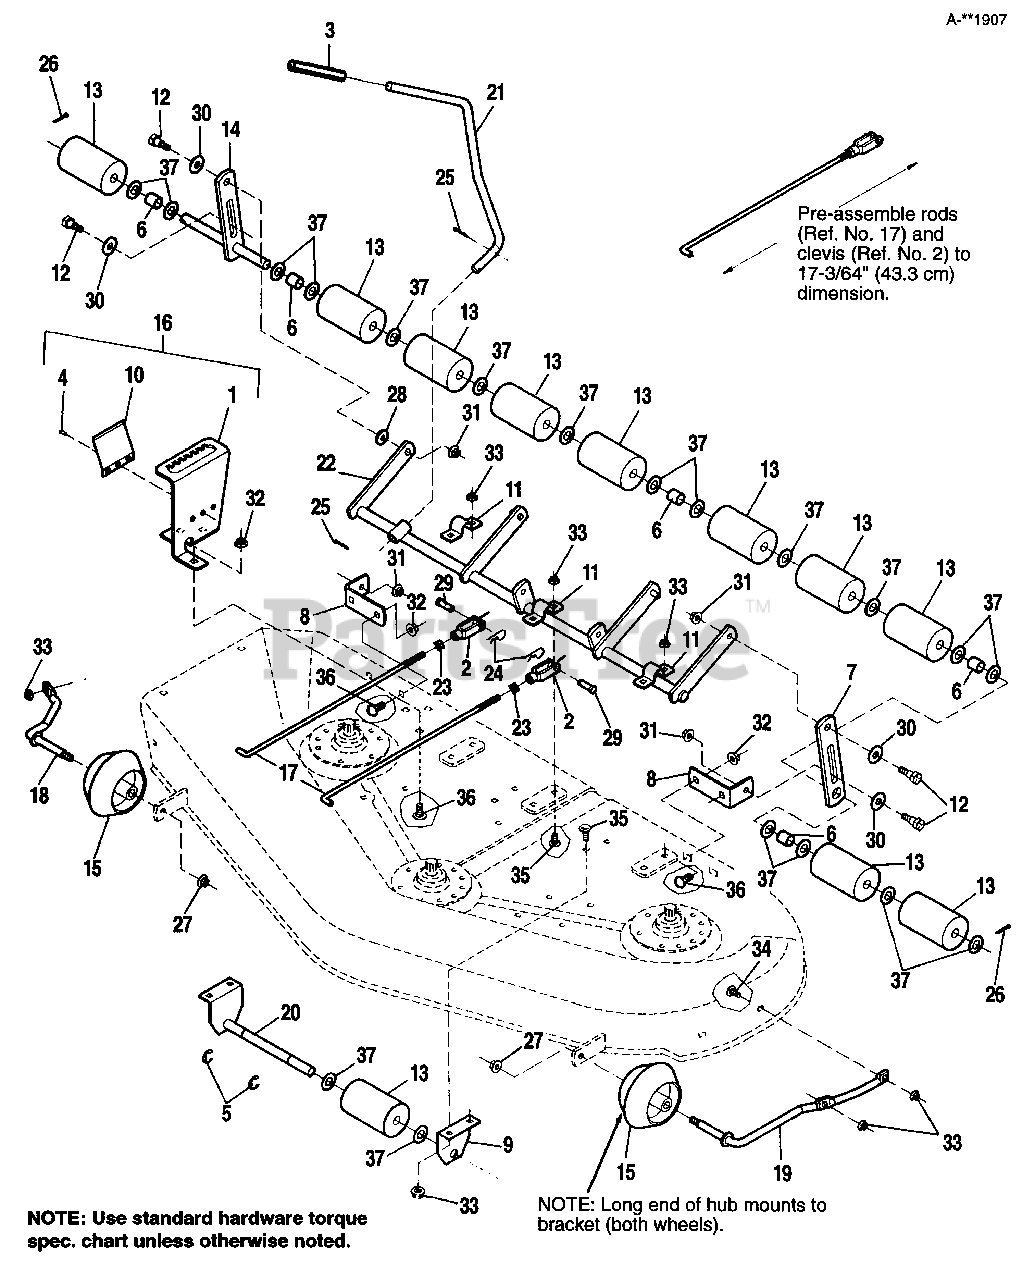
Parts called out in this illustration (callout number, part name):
2	CLEVIS, Adjusting
5	RETAINING RING
6	SPACER, .66 ID
7	BAR, Roller
8	BRACKET, Roller Support
11	STRAP
12	BOLT, Shoulder, 3/8-16 X 1.34
14	SHAFT ASSY., Roller
16	QUADRANT ASSY, (Incl. Ref. Nos. 1, 4 & 10)
17	ROD, Adjusting
18	ROD ASSY, Roller, RH
19	ROD ASSY, Roller, LH
20	SHAFT ASSY.
21	LEVER, Control
22	ARM ASSY, Mower
23	NUT, Hex, 3/8-16
24	PIN, Quick
25	PIN, Cotter, 1/8 x 1
26	PIN, Cotter
27	NUT, Hex, ESNA, Lock, 3/8-16
28	WASHER, 3/8
29	PIN, Clevis
30	WASHER, 1/2
31	NUT, Whizlock, 3/8-16
32	NUT, Hex, Whizlock, 3/8-16
33	NUT, Hex, Whizlock, 5/16-18
34	CARRIAGE BOLT, 5/16-18 x 5/8
35	CARRIAGE BOLT, 5/16-18 x 3/4
36	CARRIAGE BOLT, 3/8-16 x 3/4
37	WASHER, 5/8
